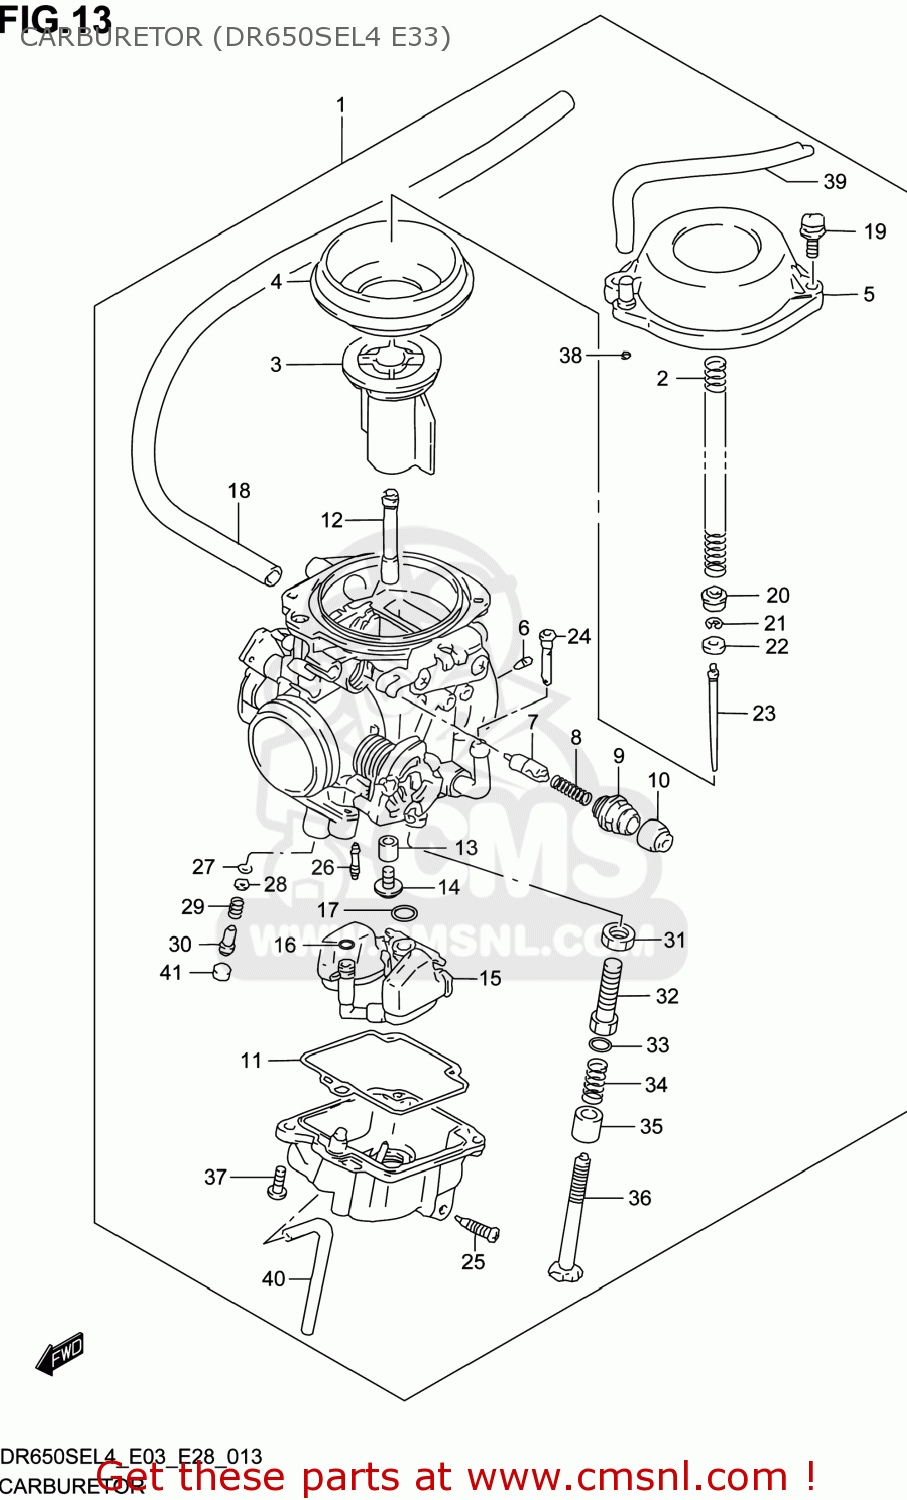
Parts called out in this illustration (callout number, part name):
1	CARBURETOR ASSY
2	SPRING
3	VALVE,PISTON
4	DIAPHRAGM
5	COVER,DIAPHRAGM
6	JET,AIR(1.0)
7	PLUNGER
8	SPRING
9	HOLDER,GUIDE
10	CAP
11	GASKET,FLOAT CHAMBER (NAS)
12	JET,NEEDLE(Y-5M)
13	RING
14	JET,MAIN(140)
15	FLOAT/NEEDLE VALVE ASSY
16	O RING
17	O RING,NEEDLE VALVE SEAT
18	HOSE(6.5X10.5X275)
19	SCREW
20	RING
21	CLIP,NEEDLE
22	RING
23	NEEDLE,JET(6F23)
24	FILTER
25	SCREW,DRAIN
26	JET,PILOT(42.5)
27	O RING,PILOT AIR SCREW
28	WASHER
29	SPRING
30	SCREW,PILOT
31	NUT
32	ADJUSTER
33	WASHER,STARTER SHAFT
34	SPRING
35	RING
36	ADJUSTER
37	SCREW(5X14)
38	O RING
39	HOSE(4.5X8.5X600)
40	HOSE(3X5X450)
41	PLUG
